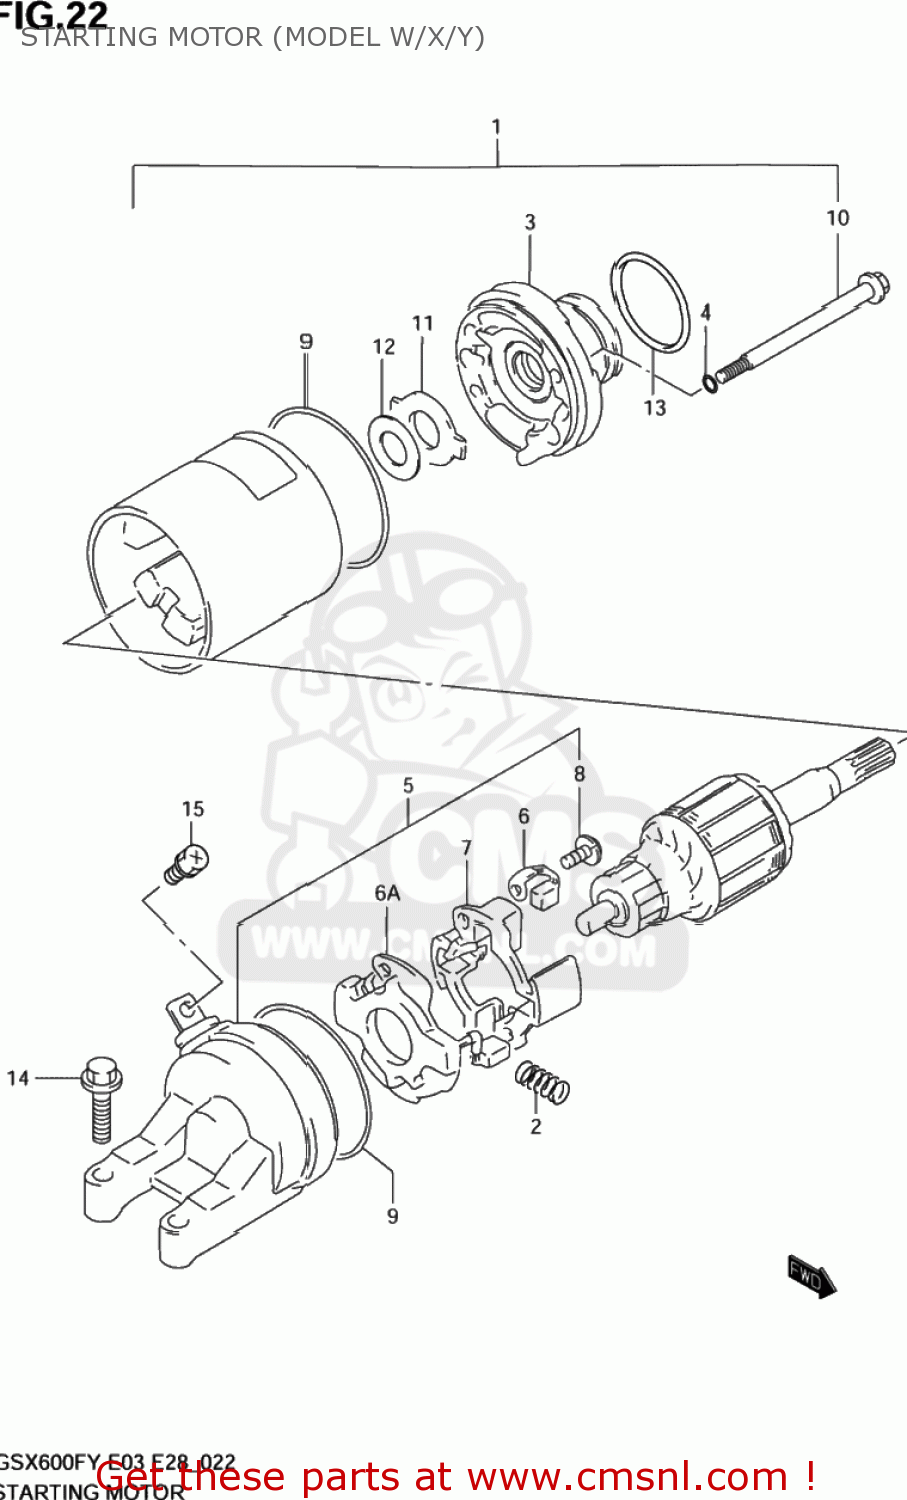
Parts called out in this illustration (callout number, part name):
1	MOTOR ASSEMBLY,STARTING
2	SPRING
3	BRACKET
4	O RING
5	FRAME ASSY,COMMUTATOR END
6	BRUSH
6A	BRUSH SUB ASSY,STARTER
7	HOLDER,BRUSH
8	SCREW
9	O RING
10	BOLT
11	PLATE,LOCK
12	SHIM
13	O RING(D:3,ID:24.5)
14	SCREW (6X25)
15	SCREW(5X8)
